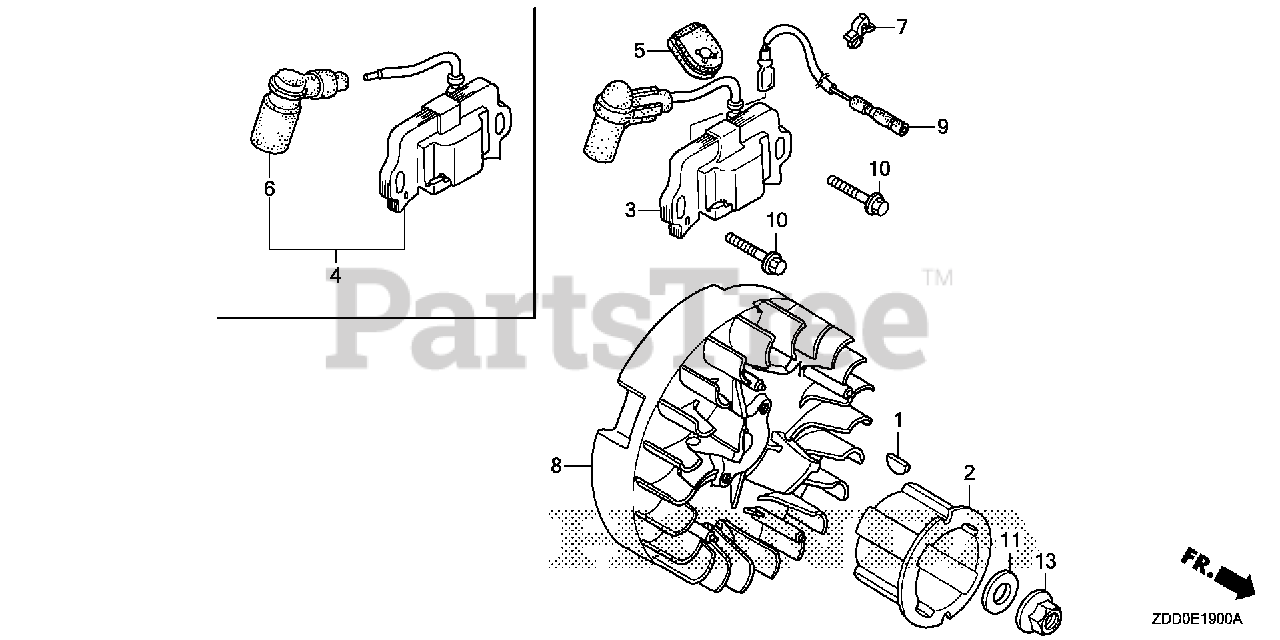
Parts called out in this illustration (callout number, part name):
1	KEY, SPECIAL
3	COIL ASSY., IGNITION
5	GROMMET, WIRE
7	CLIP, IGNITION WIRE (8MM)
9	WIRE, STOP SWITCH
10	BOLT, FLANGE (6X20) (CT200)
11	WASHER (12MM)
13	NUT, FLANGE (12MM)
